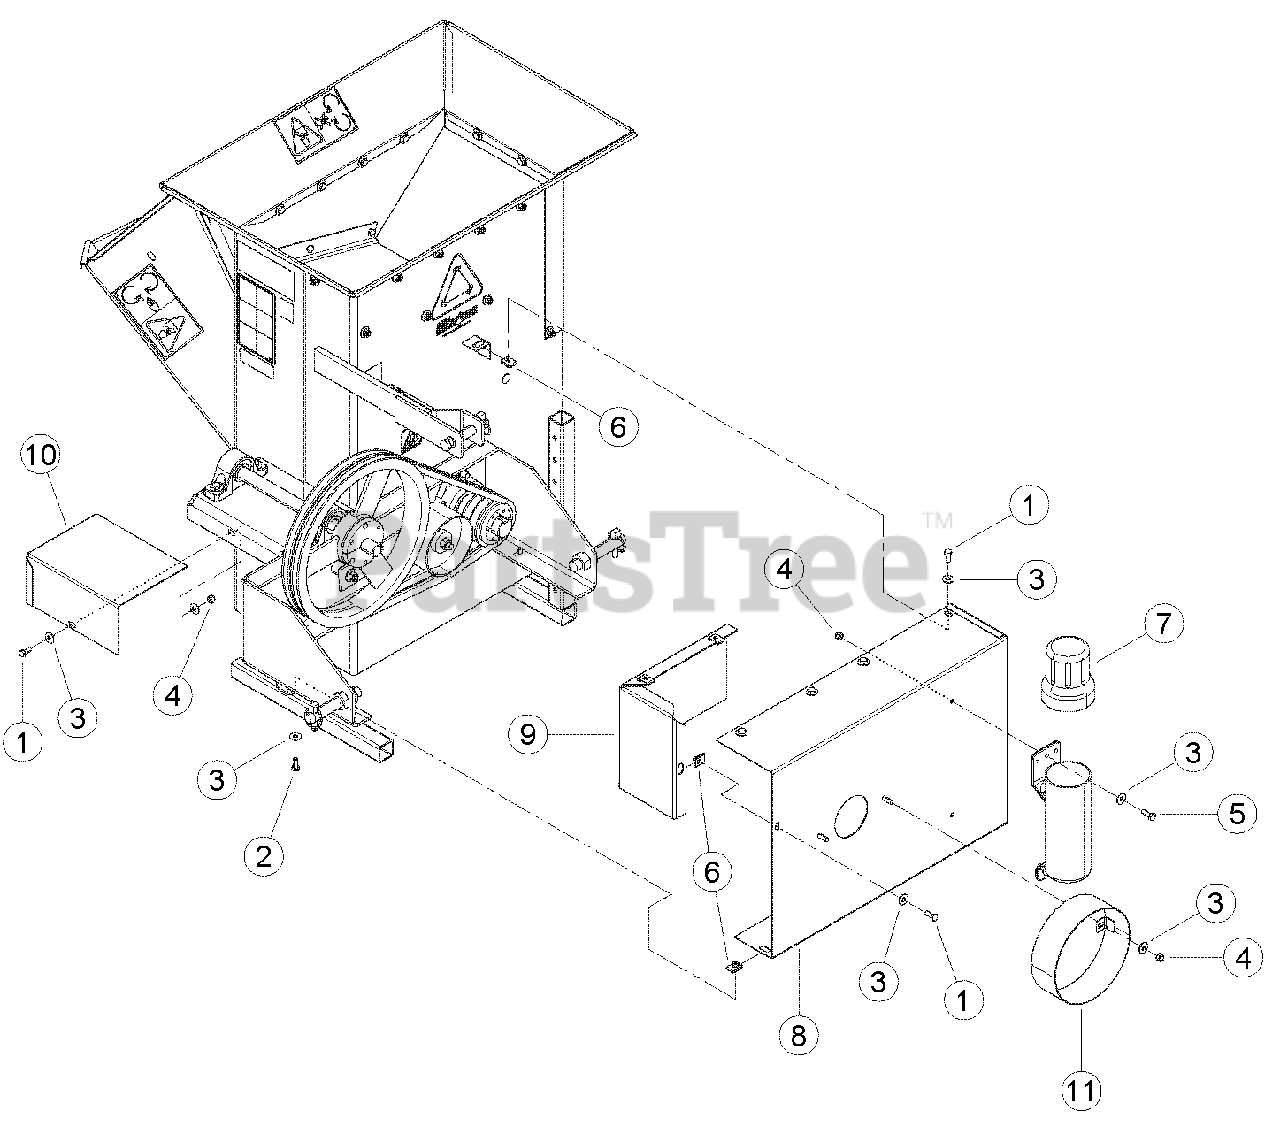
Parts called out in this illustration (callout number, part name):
1	BOLT, 5/16 X 3/4 HEX HD GR5 ZP
2	BOLT, 5/16 X 1 HEX HD GR5 NC ZP
3	WASHER, 5/16 FLAT ZP
4	NUT, 5/16 NE NYLOCK ZP
5	BOLT, 5/16 X 7/8 HEX HD NC GR5 ZP
6	NUT, 5/16-18 TINNERMAN U-TYPE
7	CONTAINER, MANUAL (WAS 18008-00, REMOVED)
8	PTO BELT GUARD WELDMENT
9	GUARD PTO END
10	WELDMENT, JACKSHAFT SHIELD
11	JOINT SHIELD WELDMENT
